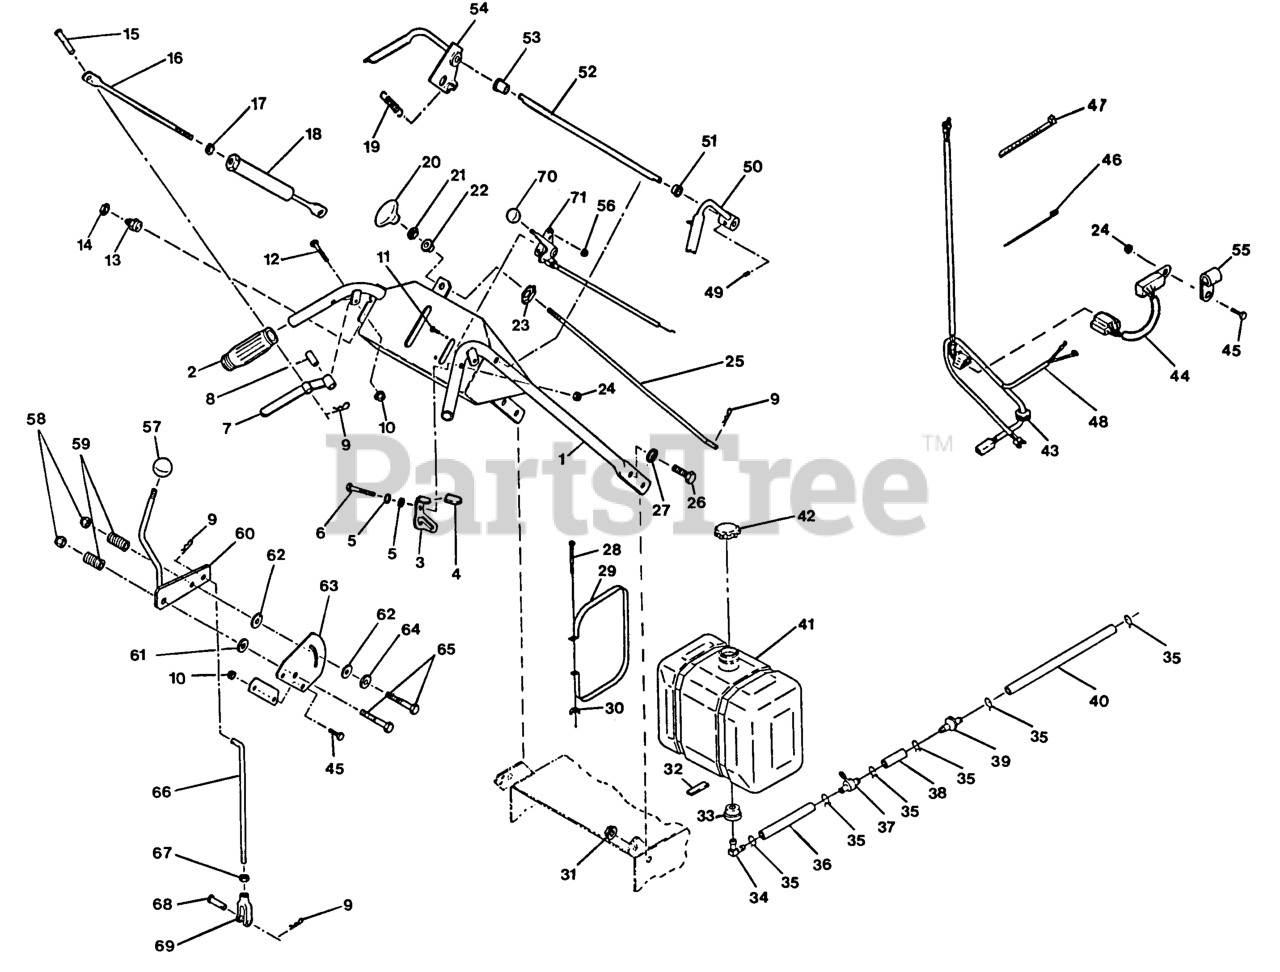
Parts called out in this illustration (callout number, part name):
4	GRIP-LATCH
5	WASHER-SPRING
8	BUSHING-LEVER, DRIVE
9	PIN-COTTER
11	BOLT-CARR
13	SWITCH,OPERATOR CNTRL
15	PIN - CLEVIS PLTD
16	ROD,DRIVE LEVER LINKAGE
19	SPRING-EXTENSION
20	KNOB-PUSH / PULL
22	BEARING-NYLON
23	NUT-PUSH
25	LINKAGE-BLADE
28	SCRW,MACH CRPH
30	WINGNUT
32	PAD,PLASTIC TANK
34	ELBOW-TANK, FUEL
36	HOSE-FUEL
37	VALVE-FUEL
38	HOSE-LINE, FUEL
40	HOSE-LINE, FUEL
42	CAP-FUEL
43	GROMMET
46	TIE-CABLE
47	TIE-PLASTIC
48	HARNESS,WIRING KAW
49	SCREW-SET
51	BUSHING-NYLON
52	ROD,CONNECTING
53	BUSHING,FLANGED
55	CLIP-LOOM
57	KNOB-BALL
63	PLATE-LEVER, SHIFTER
64	WASHER-FRICTION
66	ROD,SPEED CONTROL PLTD
68	PIN-CLEVIS
69	ARM,IDLER RH
70	KNOB-BALL
71	CABLE,THROTTLE CONTROL
